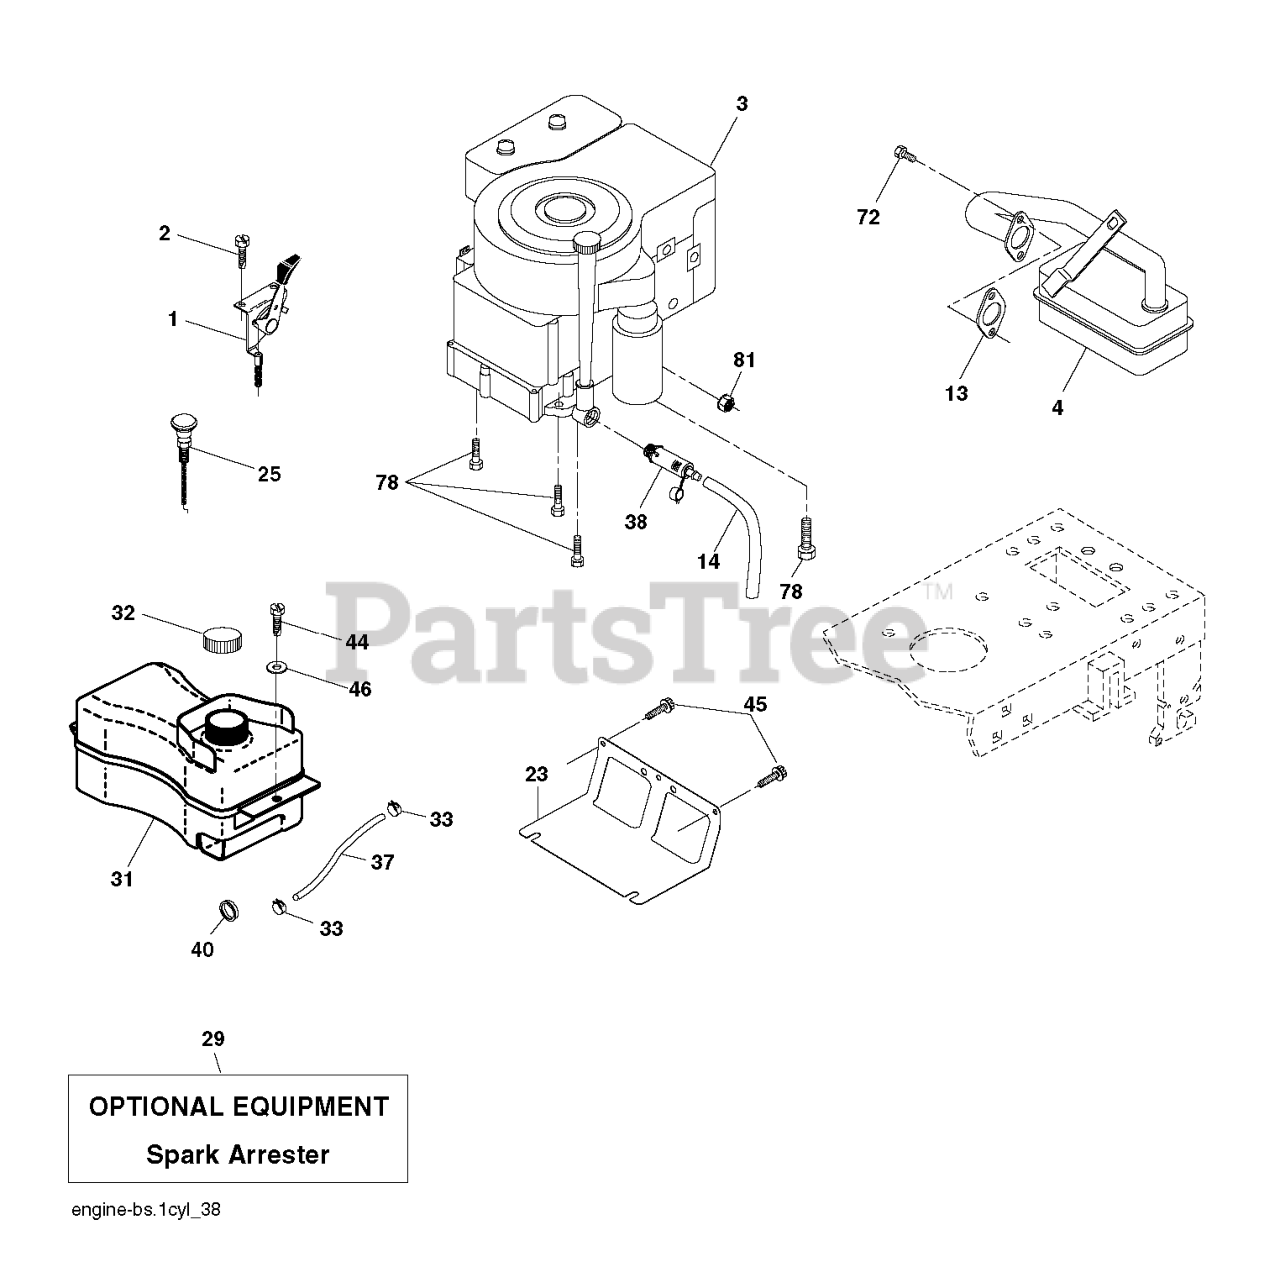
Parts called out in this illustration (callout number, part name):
1	CONTROL.THROTTLE/CHOKE.BLACK
2	SCREW
4	MUFFLER.B&S.MODEL.21.11HP.OHV
13	REPL BY 532 27 22-93
14	TUBE, DRAIN OIL ASM.
23	SHIELD.BROWNING.DBR.GUARD
25	KNOB.ERGO.EXTENDED.RED (1 2)
29	KIT.SPARK ARRESTOR 794945 B&S
32	FUEL CAP
33	HOSE CLAMP
37	LINE.FUEL.20
38	PLUG DRAIN OIL EASY
40	BUSHING.SNAP.NYL.BLK.
44	SCREW HEXWSHR 1/4-20X3/4
45	SCREW, 3/8-16X3/4
72	SCREW.SOCKET HD.5/16-1
78	SCREW.3/8-16
81	NUT
